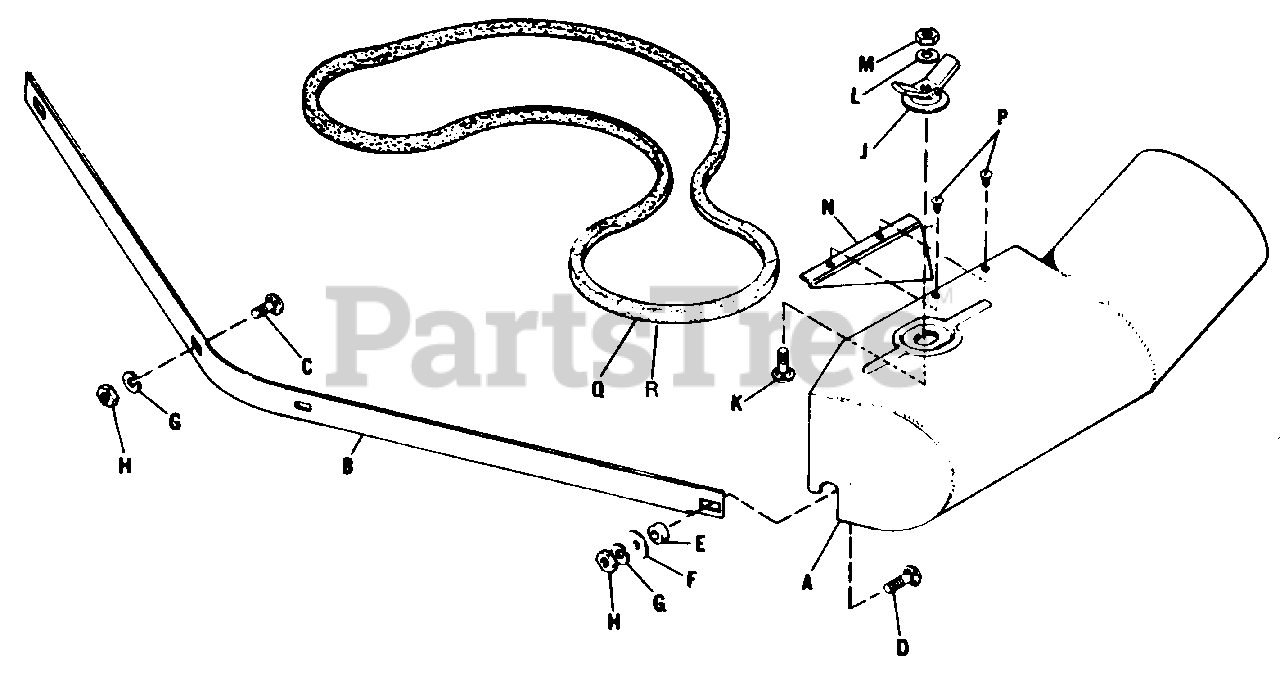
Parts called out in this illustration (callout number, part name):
A	Collector Side Housing Assembly
B	Front Baffle
C	Carriage Bolt, 3/8"-16 x 1" lg.
D	Carriage Bolt, 3/8"-16 x 1-1/4" lg.
G	Lock Washer, 3/8"
H	Nut, Hex, Full, 3/8"-16
J	Nut Assembly
K	Carriage Bolt, 3/8"-16 x 1" lg.
L	Lock Washer, 3/8"
M	Nut, Hex, Full, 3/8"-16
P	Screw, Self Tapping, No.10-24 x 1/2" lg.
Q	"V" Belt for No. 537
R	"V" Belt for No. 547
